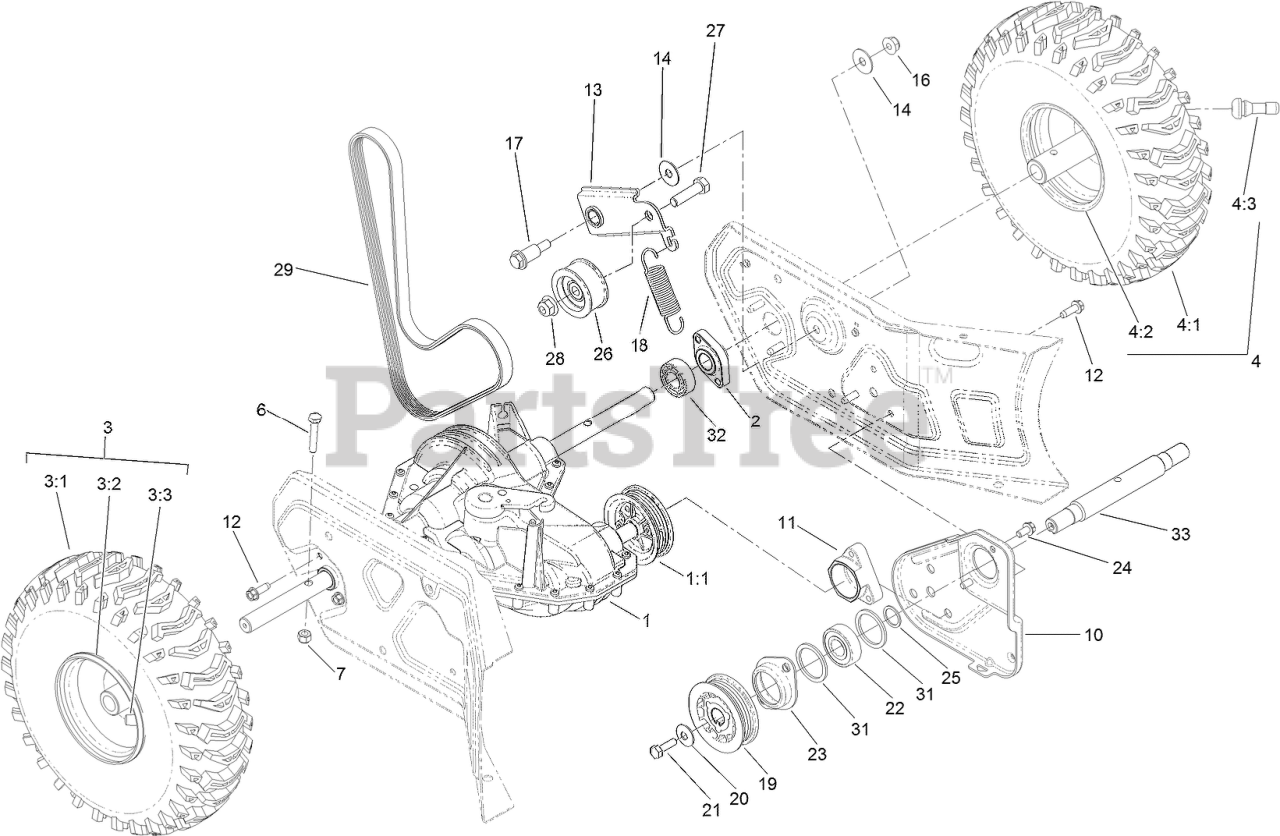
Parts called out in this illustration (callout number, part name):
1	TRANSMISSION
1:1	PULLEY REPAIR KIT
2	BEARING-AXLE
3	RH WHEEL AND TIRE ASM
3:3	STEM-VALVE
4	LH WHEEL AND TIRE ASM
4:3	STEM-VALVE
6	SCREW-HH
7	NUT-LOCK, NI
10	PLATE-SUPPORT, JACKSHAFT
11	SUPPORT-BEARING
12	SCREW-HWHTF
13	IDLER-TRACTION
14	WASHER
16	NUT-HF, NI
17	BOLT-SHOULDER, HHF
18	SPRING-EXTENSION
19	PULLEY-JACKSHAFT
20	WASHER-BELLEVILLE
21	SCREW-HH
22	BEARING-BALL
23	RETAINER-BEARING
24	SCREW-HWH
25	WASHER-THRUST
26	PULLEY-IDLER, FLAT
27	SCREW-HH
28	NUT-HF, NI
29	BELT-V
31	WASHER-RUBBER
32	SPACER-AXLE
33	JACKSHAFT
